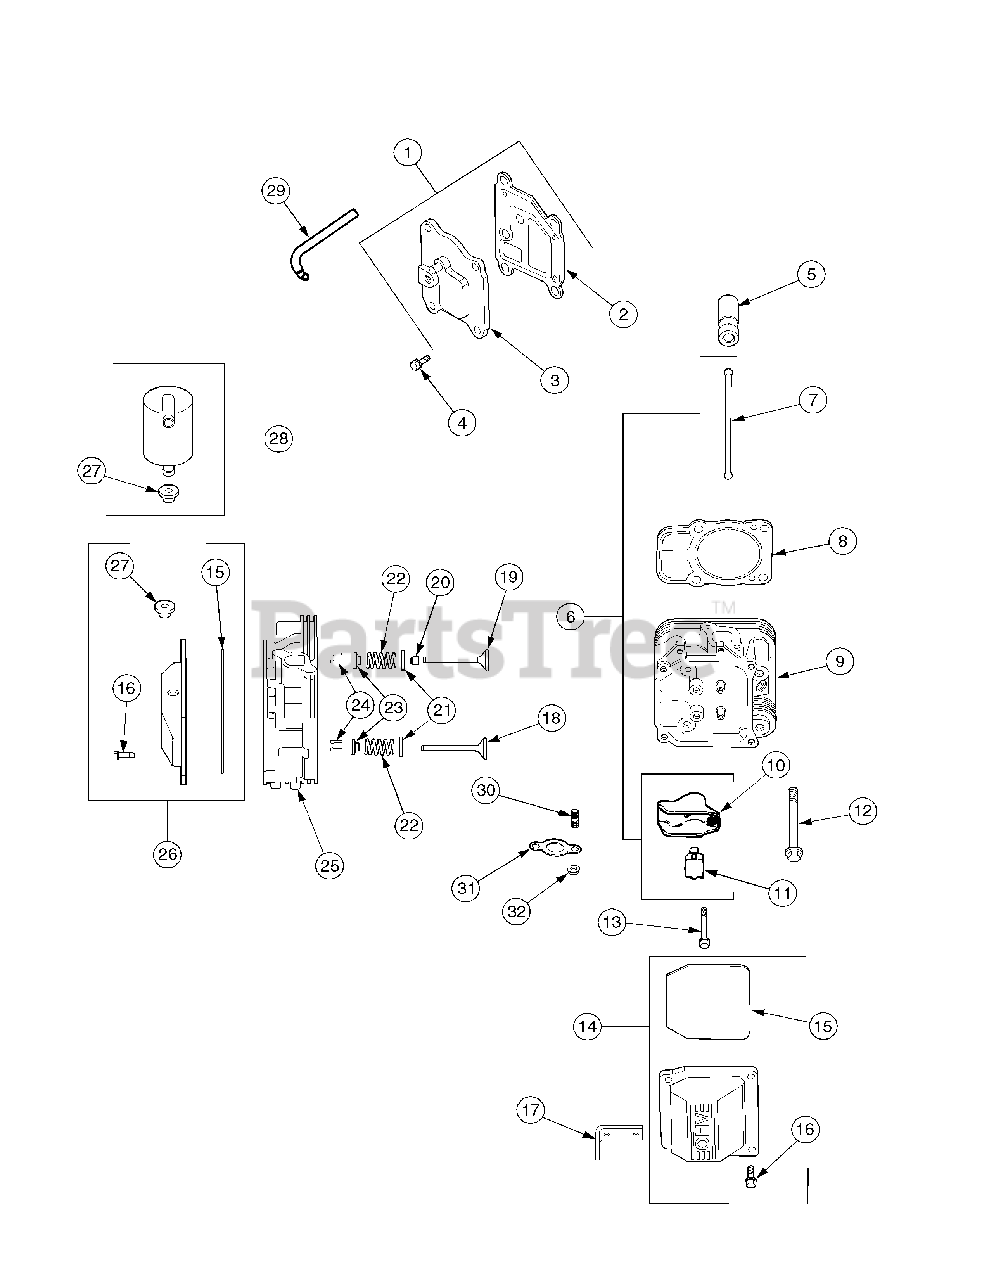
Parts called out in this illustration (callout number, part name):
1	Kit, Breather Cover
2	Gasket, Breather
3	Cover, Breather
4	Screw, Hx Flange, M6-1.0 x 20
5	Lifter, Valve
6	Kit, Valve Train
8	Kit, Cylinder Hd Gasket (Includes Head Mtg. Hardware)
9	Head Assembly, #2 Cylinder
11	Pivot, Rocker Arm
12	Screw, Hex Flange
13	Screw, Hex Flange, M6-1.0 x 34
14	Kit, Valve Cover
15	O-Ring
16	Screw, Hex Flange, M6-1.0 x 30
17	Strap, Lifting
18	Valve, Exhaust, Std
19	Valve, Intake, Std.
20	Seal, Valve Stem
21	Retainer, Spring
22	Spring, Valve
23	Cap, Valve Spring
24	Kit, Retainer
25	Head, Cylinder, #1
26	Kit, Valve Cover
27	Grommet, Rubber
28	Kit, Breather Separator
29	Hose, Breather
30	Stud, M8-1.25 x 33
31	Gasket, Exhaust
32	Nut, Muffler Mtg., M8-1.25
